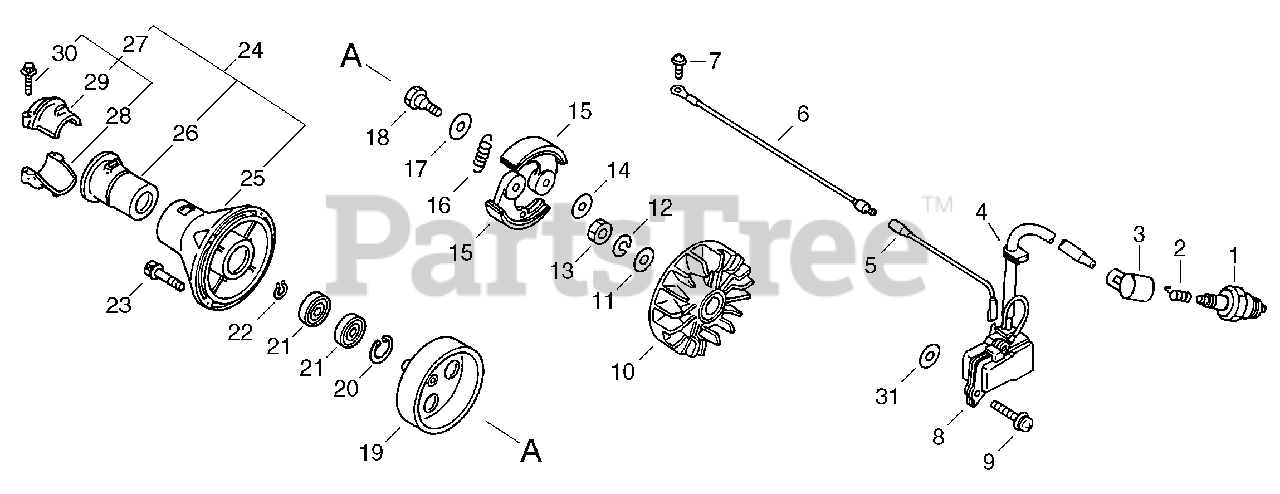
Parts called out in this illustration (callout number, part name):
1	SPARK PLUG -- RCJ-7Y
2	TERMINAL, SPARK PLUG CAP
3	CAP, SPARK PLUG
5	LEAD - IGNITION
6	LEAD - GROUND
7	SCREW - 5X10
8	COIL, IGNITION
9	SCREW - 5X20
10	FLYWHEEL
11	WASHER - 10
12	LOCKWASHER - 10
13	NUT - 10
15	SHOE, CLUTCH
16	SPRING, CLUTCH
18	BOLT, CLUTCH
19	DRUM, CLUTCH
20	RING, RETAINING - 28
21	BEARING, BALL - 6001
22	RING, RETAINING - 12
23	SCREW - 5X20
24	FAN CASE ASSY
25	CASE, FAN
27	MAIN PIPE CLAMP KIT
28	CLAMP, MAIN PIPE - LOWER
29	CLAMP, MAIN PIPE - UPPER
30	SCREW - 5X25
31	WASHER - 6
